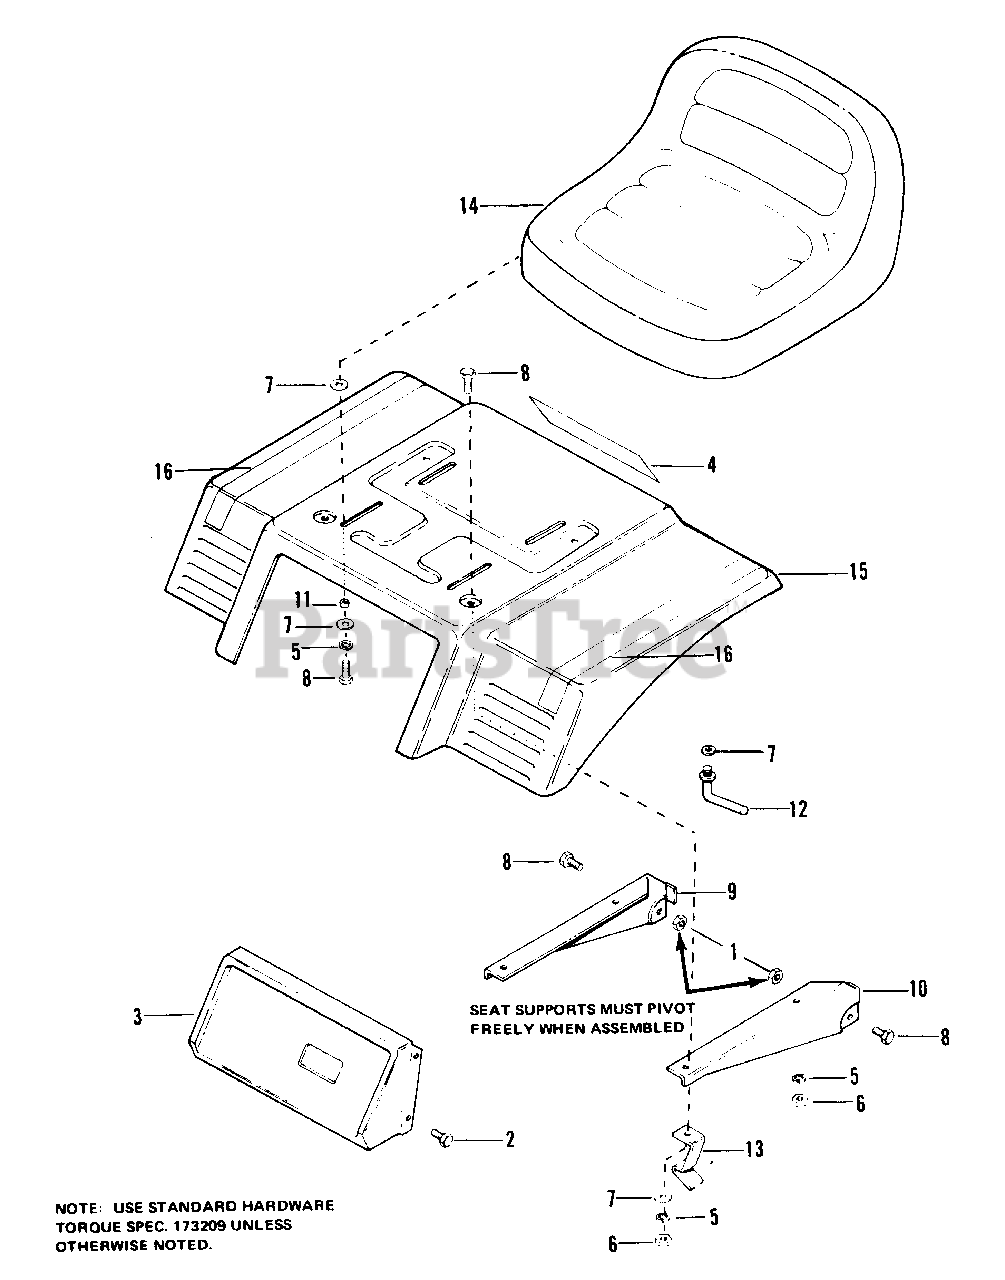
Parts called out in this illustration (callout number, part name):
1	LOCKNUT, Hex, 5/16-18
2	SCREW, Tapping, 1/4-20 x 1/2
3	PANEL, Shift
4	DECAL, Simplicity
5	LOCKWASHER, Spring 5/16
6	NUT, Hex, 5/16-18
7	WASHER, Plain 5/16
8	CAPSCREW, Hex Hd., 5/16-18 x 3/4
9	SUPPORT, R.H., Seat
10	SUPPORT, L.H., Seat
12	SCREW, Hand
13	LATCH, Spring
15	DECK, Seat
16	DECAL, Seat Deck
